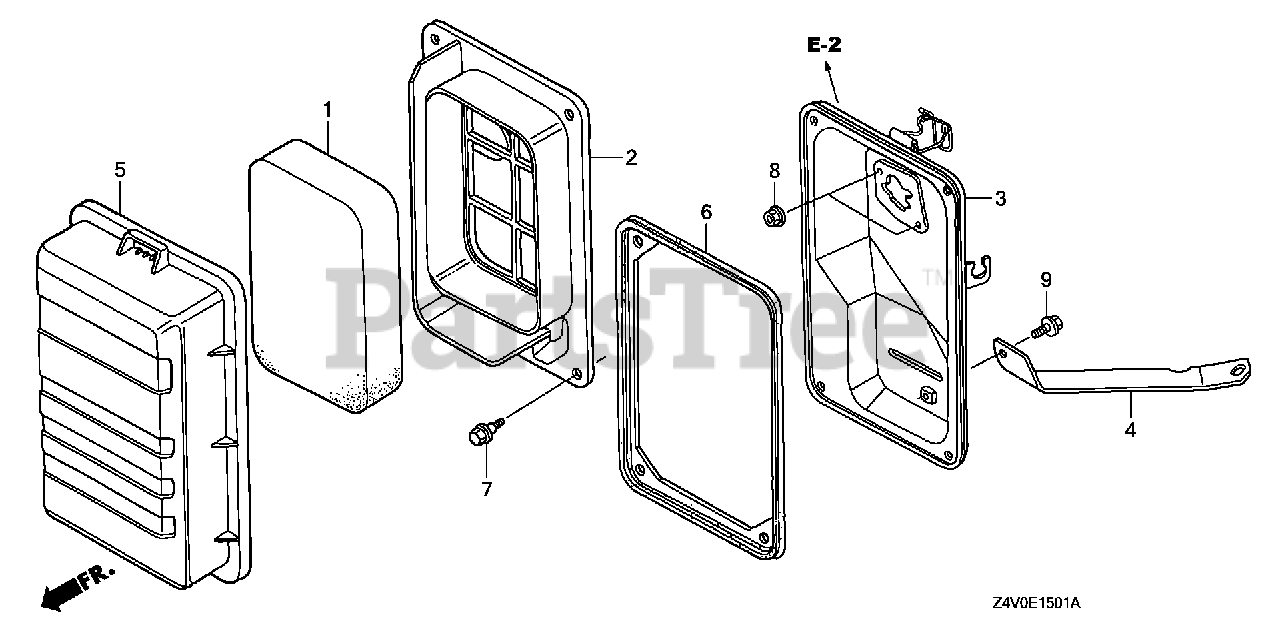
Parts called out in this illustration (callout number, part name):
1	ELEMENT, AIR CLEANER
2	SEPARATOR, AIR CLEANER
3	HOUSING, AIR CLEANER
4	STAY, AIR CLEANER
5	COVER, AIR CLEANER
6	SEAL, AIR CLEANER
7	BOLT, TURN SIGNAL SETTING
8	NUT, FLANGE (6MM)
9	BOLT, FLANGE (6X10)
